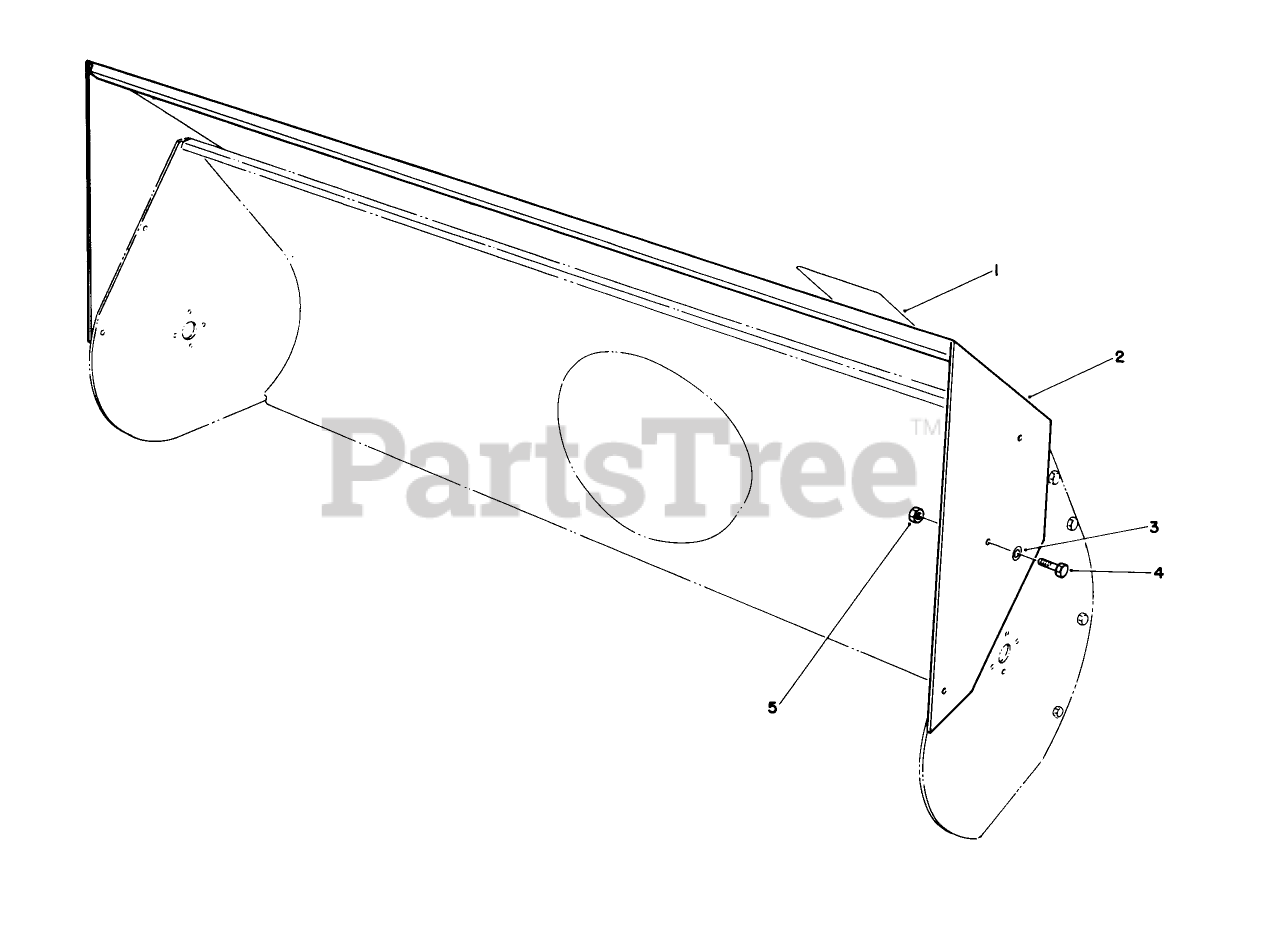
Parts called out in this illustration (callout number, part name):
1	DECAL-WARNING, AUGER
3	WASHER-FLAT
4	SCREW-HH
5	NUT-LOCK, NI
